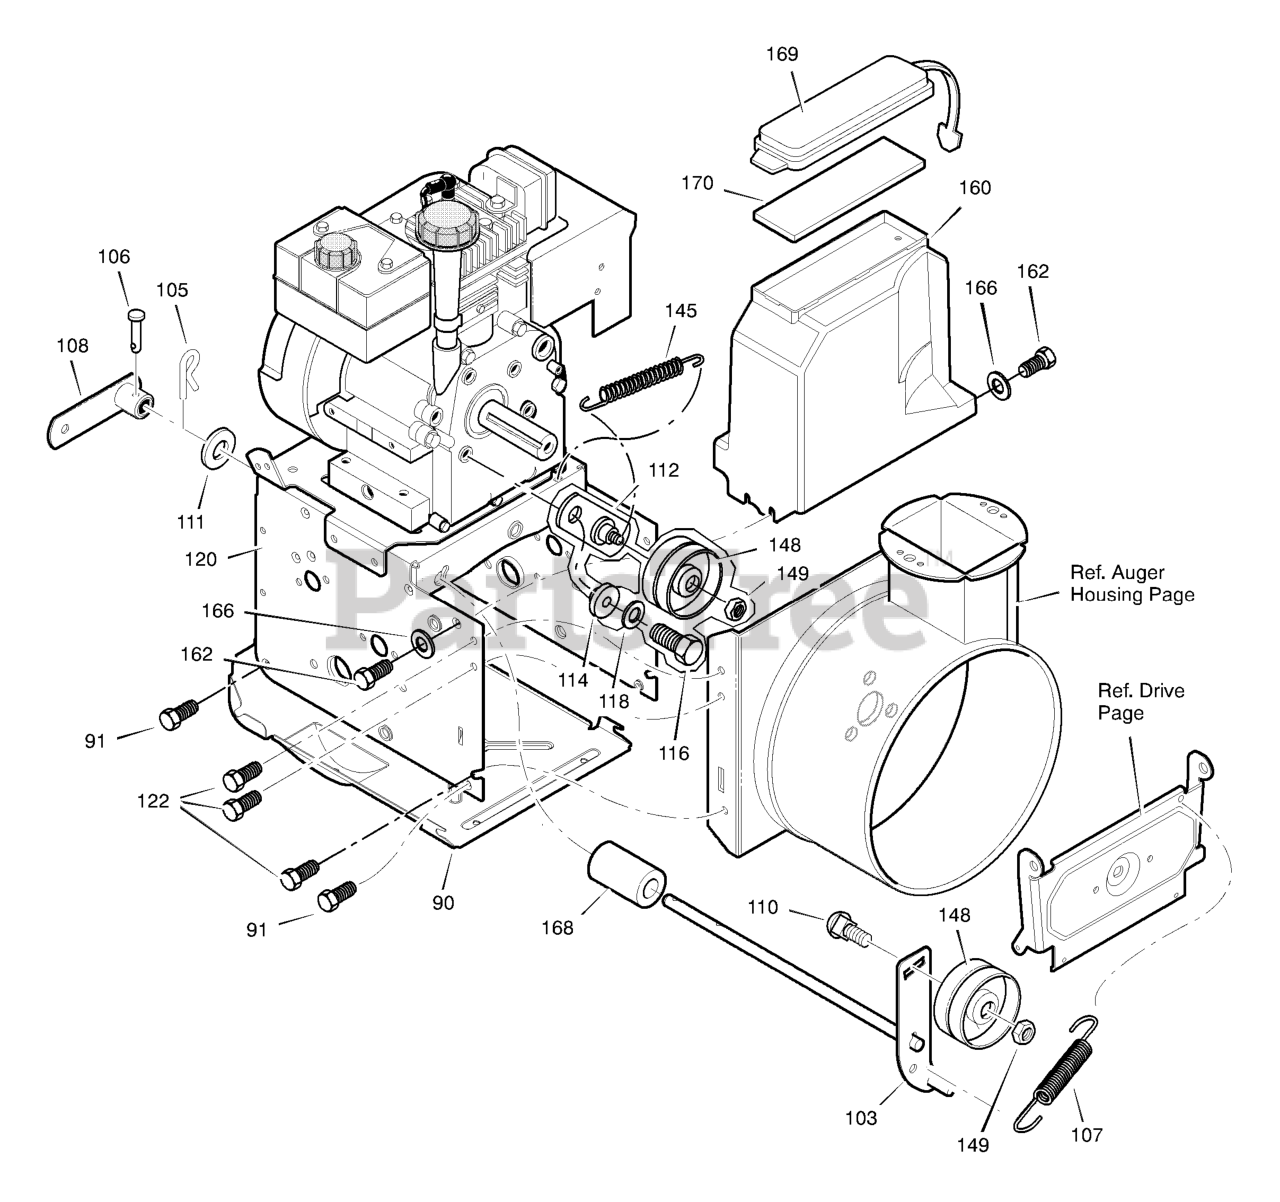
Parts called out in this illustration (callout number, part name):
90	COVER, BOTTOM
91	SCREW, 1/4-20X .63
103	IDLER ASSEMBLY, AUGER
105	PIN, HAIR .38DIAX1.64LG
106	PIN, CLEVIS 3/16 DIA
107	SPRING, TENSION
108	ASSY., SPRING ATTACH
110	BOLT, 3/8-16X1.25 CARR.
111	WASHER, FLAT
112	BRACKET ASSEMBLY, IDLER
114	BUSHING, IDLER BRACKET
116	SCREW 5/16-24 X .75
118	WASHER, SPLIT
122	SCREW, TAP 5/16-18 X .50
145	SPRING, IDLER TRACTION DRIVE
148	PULLEY, IDLER
149	NUT, JAM 3/8-16
160	COVER, BELT
162	SCREW, HEX HEAD 1/4-20 X .62
166	WASHER, FLAT
168	SPACER, AUGER BRACKET
169	COVER,TOOLBOX
170	PAD, FOAM
